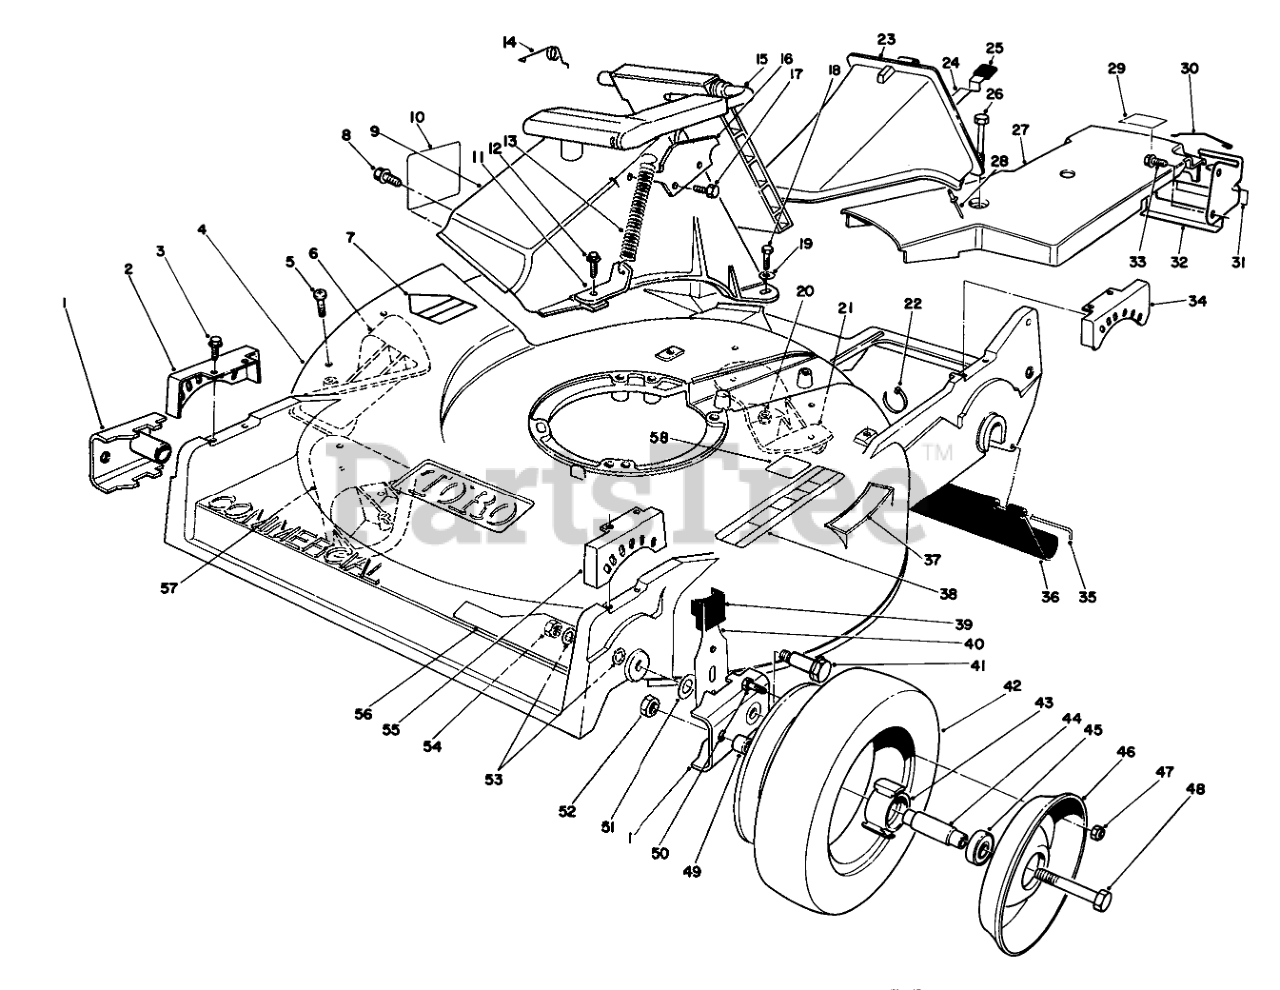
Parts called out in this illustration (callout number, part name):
1	ARM-PIVOT, FRONT
2	QUADRANT-FRONT, RH
3	SCREW-HWHTF
4	Housing-Commercial (Incl. Ref. #7, 37 & 38)
5	SCREW-PPH
6	KICKER-RH
7	Decal Danger
8	SCREW AND WASHER ASM
9	Chute-Discharge
10	DECAL - DANGER
11	BRACKET-SPRING
12	SCREW-HWH
13	SPRING-DOOR
14	RETAINER-DOOR
15	DOOR ASSEMBLY
16	DOOR LATCH PLATE
17	SCREW-PLASTITE
18	SCREW-HH
19	WASHER-FLAT
20	NUT-LOCK, NI
21	KICKER-REAR
22	TIE-CABLE
23	Plug Assembly (Incl. Ref. #24, 25, & 28)
24	LATCH-PLUG, DISCHARGE
25	GRIP-LATCH
26	SCREW-HHFTF
27	COVER-BELT
28	RIVET-HEAD, FLAT
29	Label-Grease
30	RETAINER-CABLE
31	DECAL-POSITION, GEAR
32	BRACKET-ADJUSTMENT, TRACTION
33	SCREW-HWHTF
34	QUADRANT-REAR, LH
35	ROD-SHIELD
36	SHIELD-TRAILING
37	DECAL - STEP PAD INT'L
38	Decal-Safety Instructions
39	KNOB-ARM
40	FRONT SPRING ARM ASM
41	BOLT-WHEEL
43	HUB-BEARING
44	SPACER-BEARING
45	BEARING-WHEEL
46	Wheel-Half
47	NUT-LOCK, NI
48	SCREW-HH
49	SPACER-WHEEL
50	SCREW-HH
51	WASHER-THRUST
52	NUT-LOCK, CONE
53	WASHER
54	NUT-LOCK
55	QUADRANT-FRONT, LH
56	DECAL - RECYCLER
57	KICKER-FRONT
58	Decal-Noise Level
